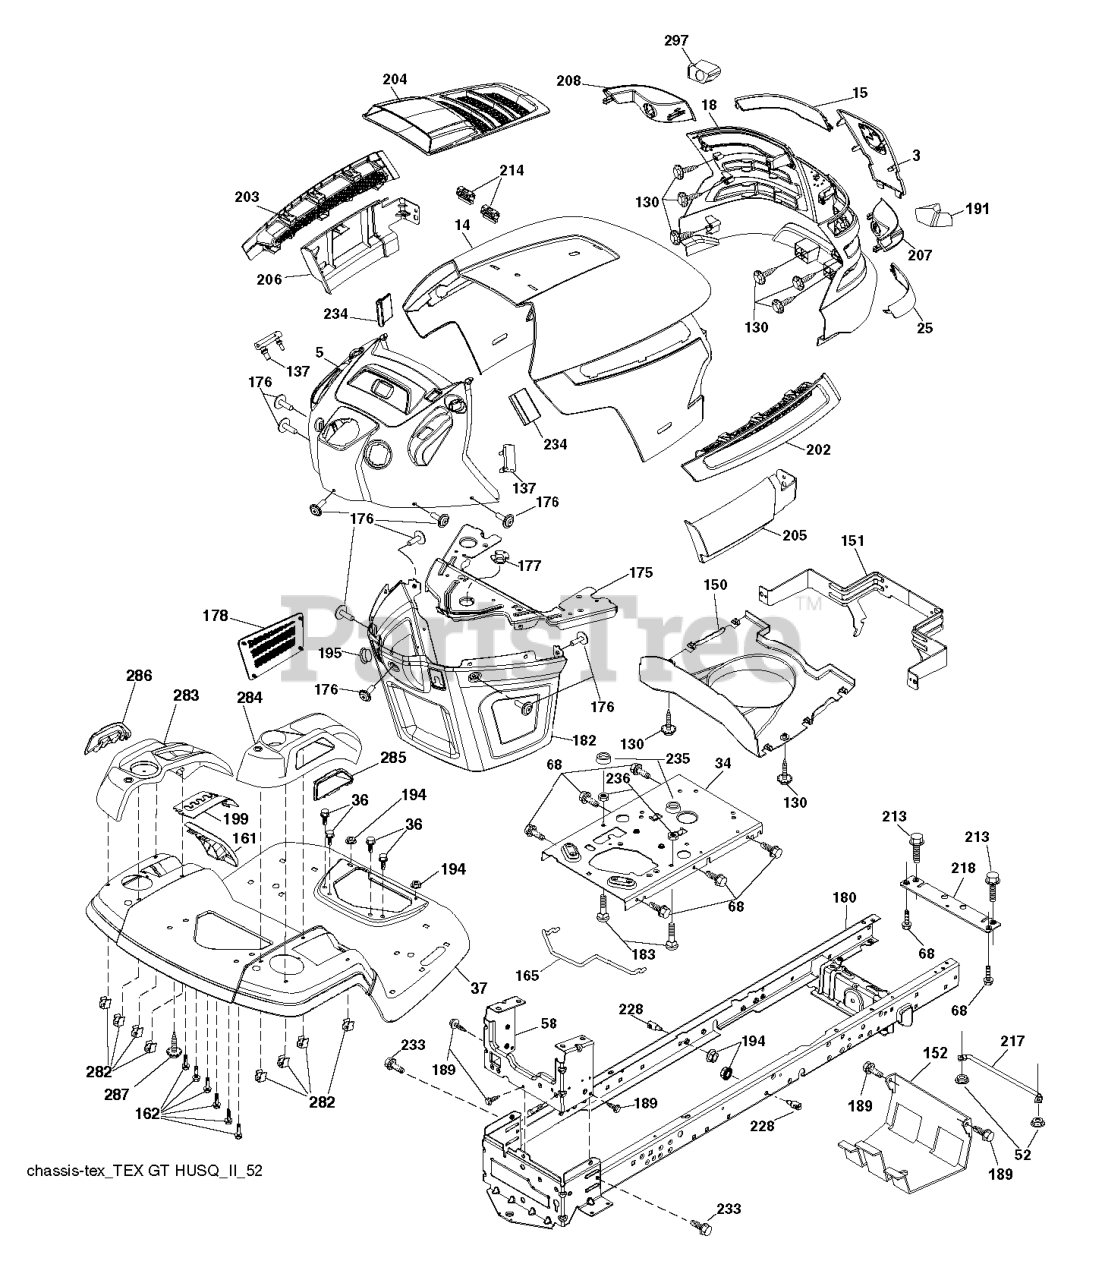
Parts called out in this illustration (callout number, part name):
3	APPLIQUE.SUBASM.GT.HUSQ.II
5	DASH.UPR.ASSY.GT2.SRVMNDER.PTO
14	HOOD.ASM.HUSQVARNA.GT.TEX.ORAN
15	LENS.HEADLIGHT.LH.GTII.2011
18	GRILLE.SUBSTRATE.2011.
25	LENS.HEADLIGHT.RH.GTII.2011
34	PLATE.ENGINE.WELDED.CHASSIS
36	SCREW 5/16"
37	FENDER.TLT.FS.W/CPH/FW/RSF.668
52	LOCKNUT
58	DRAWBAR UPPER 2PC SMALL FENDER
68	Screw 5/16-18 x 1/2 Hex, Self Tapping 5/16-18 x 1/2
130	SCREW.#10 X 0.750.BOS
137	BUMPER DASH
150	AIR.DUCT.GTV.BLACK
151	BRACKET.PIVOT.HOOD.GT.HUSQ.II
152	SHIELD.BROWNING.W/TEX
161	WINDOW.FUEL.LT.HUSQ.TEX.498
162	SCREW.HI-LO.CONSOLE
165	SUPPORT.TANK.REAR.W/TEX
175	PLATE.CROSSMEMBER.HUSQ
176	SCREW.#10-24X5/8.RN.QU
177	BUSHING, STEERING
178	CARGO.ASM.NET.TXGT.W/C
180	CHASS.WLDMNT.TL.12GA/2P.48/54
182	DASH.LOWER.COMMON.12V.ADAPTOR
183	BOLT.5/16-18X1-1/4 FULL THD
189	SCREW
191	INSERT.REFLECTIVE.RH.HUSQ.GTII
194	NUT LOCK HEX FLANGE 5/16-18
195	PLUG.HOLE.DASH.LOWER.12V.BLK
199	PLATE.DECK.LIFT.HUSQ.LT
202	VENT.SIDE.RH.GT.HUSQ.II.
203	VENT.SIDE.LH.GT.HUSQ.II.498
204	VENT.TOP.HUSQ.GT2
205	SIDE.TRIM.RH.GT.HUSQ.II
206	SIDE.TRIM.LH.GT.HUSQ.II.GRAY
207	BEZEL LIGHT.RH.GT.II.MYLAR
208	BEZEL LIGHT.LH.GT.II.MYLAR
213	BOLT
214	CLIP.RETAINER.TINNER.
217	ROD.PIVOT.HOOD
218	X-PIECE.HOOD.STOP.NON/
228	STUD.FASTNER.W/ANTI-ROTATE
233	BOLT.SHOULDER
234	BUMPER.HOOD.TEX.HUSQVARNA
235	SPACER FENDER
236	NUT.CENTERLOCK.5/16-
282	CLIP.RETAINER.CONSOLE.LT.HUSQ
283	CONSOLE.DECK.LIFT.R.SDFL.HUSQ
284	CONCOLE.CNTRL.PDL.HUSQ.LT.498
285	CONSOLE INSERT RH
286	CONSOLE.INSRT.LH.HUSQ.LT.BLACK
287	SCREW 1/4X20
297	INSERT.REFLECTIVE.LH.HUSQ.GTII
